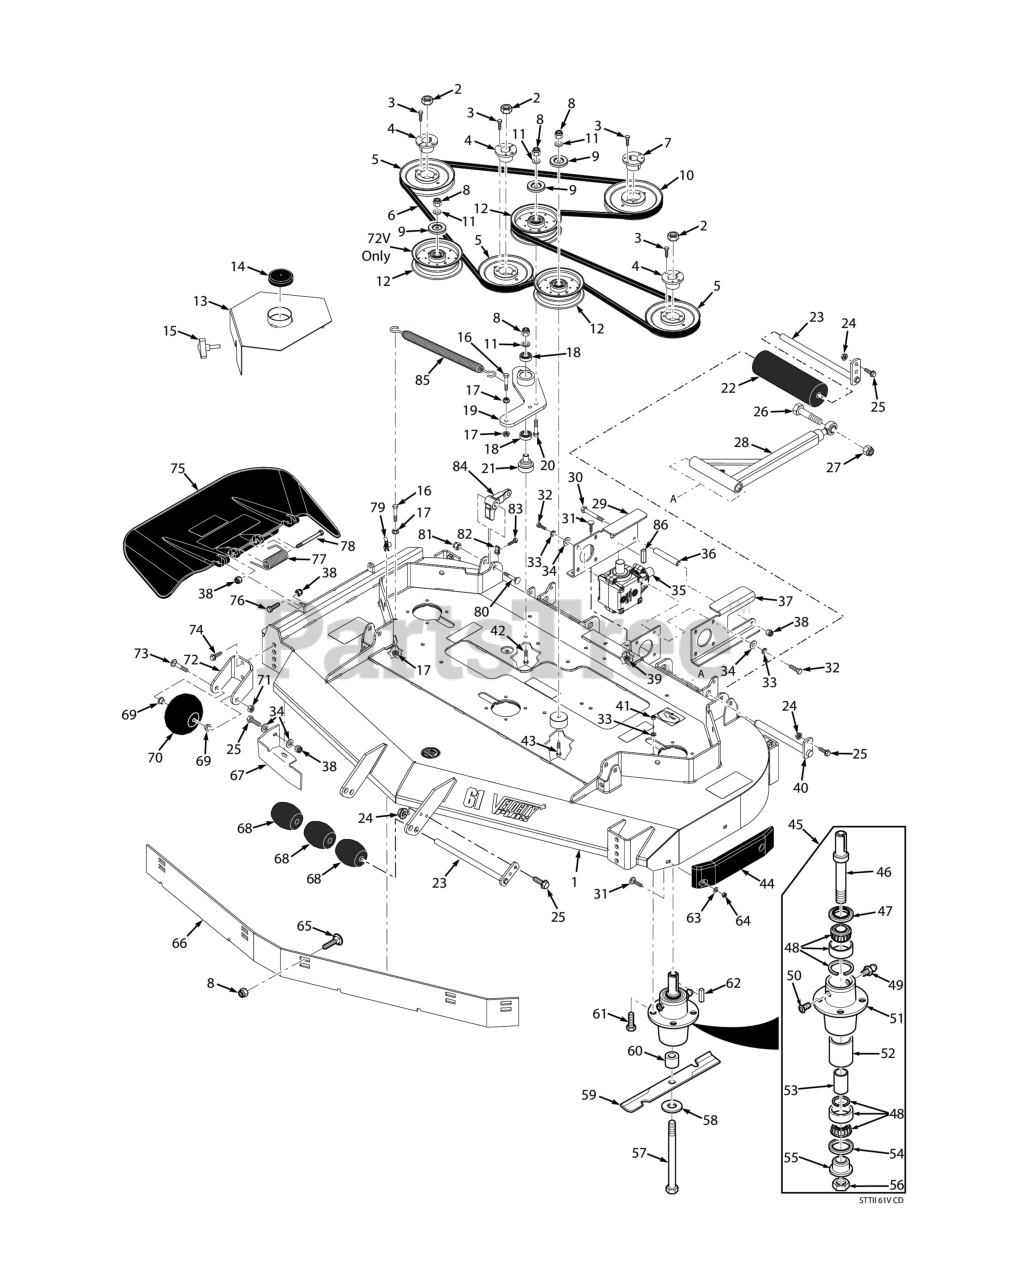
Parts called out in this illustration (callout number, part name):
1	Cutter Deck w/Decals - 61V
2	Hex Locknut, Elastic Stop, 3/8-16
3	Bolt, Hex Head 1/4-20 x 1" Grade 8 Black
4	Hub, Tapered 1-1/8" Bore
5	Pulley, 6.35 O.D. (Diesel Engine)
6	Belt, Cutter Deck Drive - Kubota
7	TAPERED HUB, 1.00" BORE
8	HEX NUT, ELASTIC STOP LOCK, 3/8-16
9	Quick Pin, 5/16" Dia.
10	Pulley, 6.75 O.D. - 61"
11	Flatwasher, 3/8 (.391 x .938 x .105 HD) Grade 8
12	Idler Pulley, Belt Clutch
13	Belt Cover, 61V (incl. #14)
15	Knob, w/stud 3/8-16 x 1-1/4"
16	Bolt, Hex Head 3/8-16 x 1-1/2" Grade 8 Black
17	NUT, 3/8-16 SERRATED FLANGE HEX HEAD
18	BEARINGS, BALL, NEUTRAL RETURN
19	Idler Arm, Cutter Deck
20	Capscrew, Hex Head 3/8-16 x 2.75"
21	Pivot, Idler - Short
22	Wheel, Anti-ScalpRelief Fitting, Tapered Spindle
23	Shaft Weldment, Guide Roller
24	Nut, Flange Head Elastic Stop 5/16-18
25	Bolt, Heax Head 5/16-18 x 1" (48V / 52V)
26	BOLT, HEX HEAD 5/8-11 X 4-1/2"
27	HEX LOCKNUT, ELASTIC STOP, 5/8-11
28	Push Arm (Includes 64,60,62)
29	Mounting Plate
30	Bolt, 5/16-18 x 4-3/4" Hex Head
31	Bolt, 5/16-18 x .75 RHSN Carriage
32	Bolt, Heax Head 5/16-18 x 1" (48V / 52V)
33	Lockwasher, 5/16 (.317 x .586 x .078) Helical Spring
34	Flatwasher, 5/16-.375 x .875 x .083 (35BV & 37BV-EFI)
35	Gearbox Assembly, Deck Drive
36	Spacer, Gearbox Mount
37	Mounting Plate
38	HEX NUT, ELASTIC STOP LOCK, 5/16-18
39	Nut, Serrated Flange 5/16-18 (Right Front Engine Mounting, Briggs and Kohler Only)
40	Shaft Weldment, Pusharm
41	Lock Nut, 5/16-18 Elastic Stop Grade 8
42	Bolt, Hex Head 3/8-16 x 3" - 52"
43	Capscrew, Hex Head 3/8-16 x 3-3/4"
44	Pad, Deck Wear
45	Cutter Spindle Assembly
46	Spindle Shaft, Tapered Brng
47	SEAL, 2.00 O.D. X 1.50 BORE
48	Tapered Bearing Set (Two Bearings W/Race)
49	GREASE FITTING, STR. 1/4-28 SELF TAP.
50	RELIEF FITTING, TAPERED BEARING SPINDLE
51	Housing, Spindle
52	Spacer, Outside, Cutter Spindle
53	SLEEVE, CUTTER SPINDLE
54	Seal, 2.00" O.D. x 1.625" Bore
55	SPINDLE BUSHING, BOTTOM
56	Nut , Spec ial 1 -1/ 1 6 - 1 8
57	BOLT, HEX HEAD, 5/8-11 X 9-1/2 GR.5
58	Flatwasher, 5/8-.688 x 1-3/4 x .134 HD
59	Cutter Blade, 21" Standard
60	Spacer, Spindle Bottom
61	Bolt, Hex Head 5/16-18 x 1-3/4" Grade 8
62	Key, 1/4 x 1/4 x 2.0"
63	Flatwasher, 5/16-.344 x .688 x .065 (48V / 52V)
64	Nut, Center Lock, 5/16-18(32)
65	Carriage Bolt, 3/8-16 x 1.0"
66	Baffle Custom-Cut, 61V (7-Position)
67	Turbo Baffle, Bolt On
68	Wheel, Anti-Scalp
69	Bushing, .376" I.D. Oilite
70	Bolt, Carriage 3/8-16 x 4"
71	Bolt, Hex Head 3/8-16 x 1" Ser. Flg.
72	Bracket, Anti-Scalp Wheel
73	Bolt, Hex Head 3/8-16 x 3-1/2"
74	Capscrew, 3/8-16 x 1.0" Serrated Flange Hex Hd
75	Discharge Chute Advantage - Large
76	Bolt, Hex Head 5/16-18 x 1-1/2" - Front
77	Spring, Discharge Chute
78	Bolt, 5/16-18 x 4-3/4" Hex Head
79	U-Nut, 3/8-16
80	Bolt, Carriage 7/16-14 x 2-1/4"
81	HEX LOCKNUT, ELASTIC STOP, 7/16-14
82	U-Nut, 3/8-16 (short)
83	Bolt, Hex Head 3/8-16 x 2" Special Lock
84	Lever, Deck Level
85	Spring, Cutter Deck
86	Key, 1/4 x 1/4 x 1.25" Pulley Mtg.
